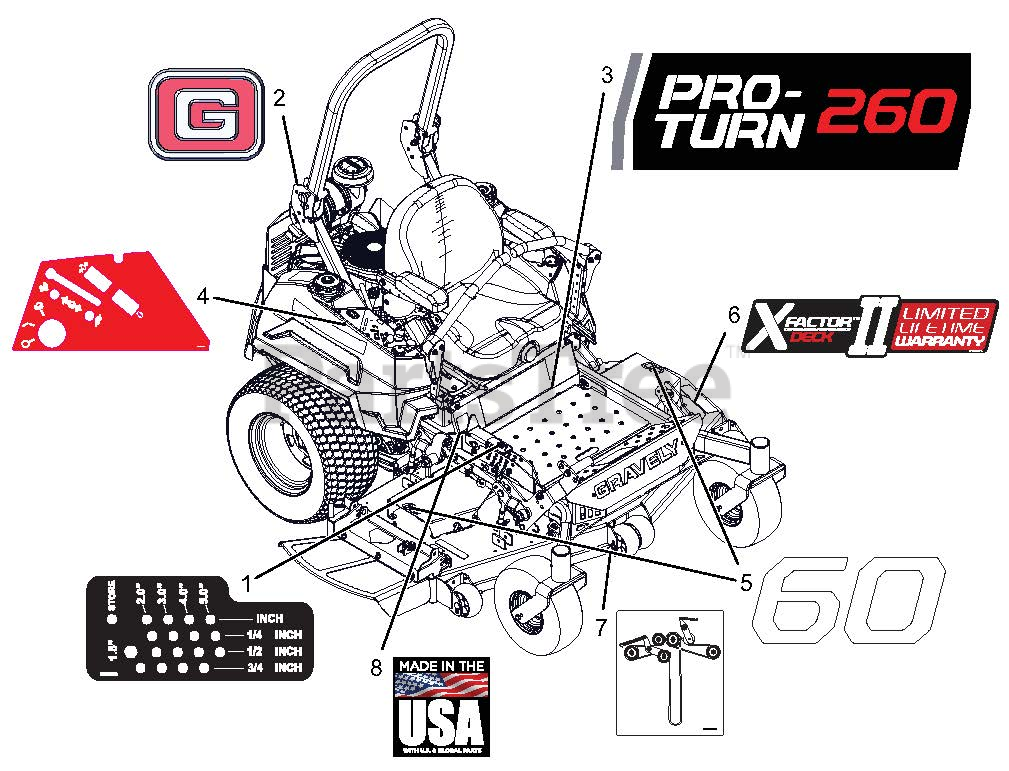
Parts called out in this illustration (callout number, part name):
1	DECAL, HEIGHT OF CUT
2	DECAL, GRAVELY BRAND
3	DECAL, PRO-TURN 260
4	DECAL, EFI CONTROL PANEL
5	DECAL, 60"
6	DECAL, X-FACTOR DECK
7	DCL,BELT ROUTE-RH BK-SIDE IDLR
8	DECAL, MADE IN USA
